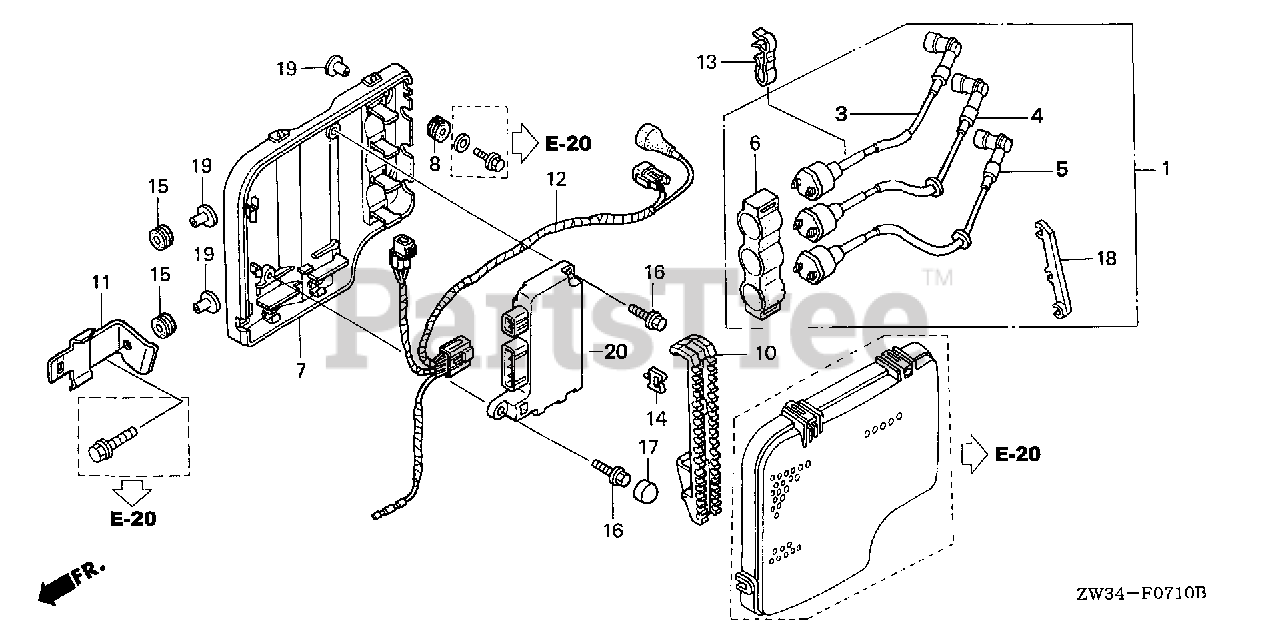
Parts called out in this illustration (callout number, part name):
1	COIL ASSY., IGNITION
3	COIL, IGNITION (1)
4	COIL, IGNITION (2)
5	COIL, IGNITION (3)
6	SUSPENSION, IGNITION COIL
7	CASE, IGNITION CONTROL MODULE (CDI)
8	GROMMET, MODULE IGNITION CONTROL CASE (CDI)(B)
10	BRACKET, CONNECTOR (A)
11	BRACKET, FUSE
12	CABLE ASSY., IGNITION CONTROL MODULE (CDI)
13	CLAMP, WIRE
14	CLIP, TURN SIGNAL WIRE
15	GROMMET, CASE (LOWER)
16	BOLT, FLANGE (6X20)
17	CAP, BOLT (6MM)
18	CLIP, HIGH TENSION CORD
19	COLLAR, MODULE IGNITION CONTROL CASE (CDI)
20	MODULE, IGNITION CONTROL (CDI)
